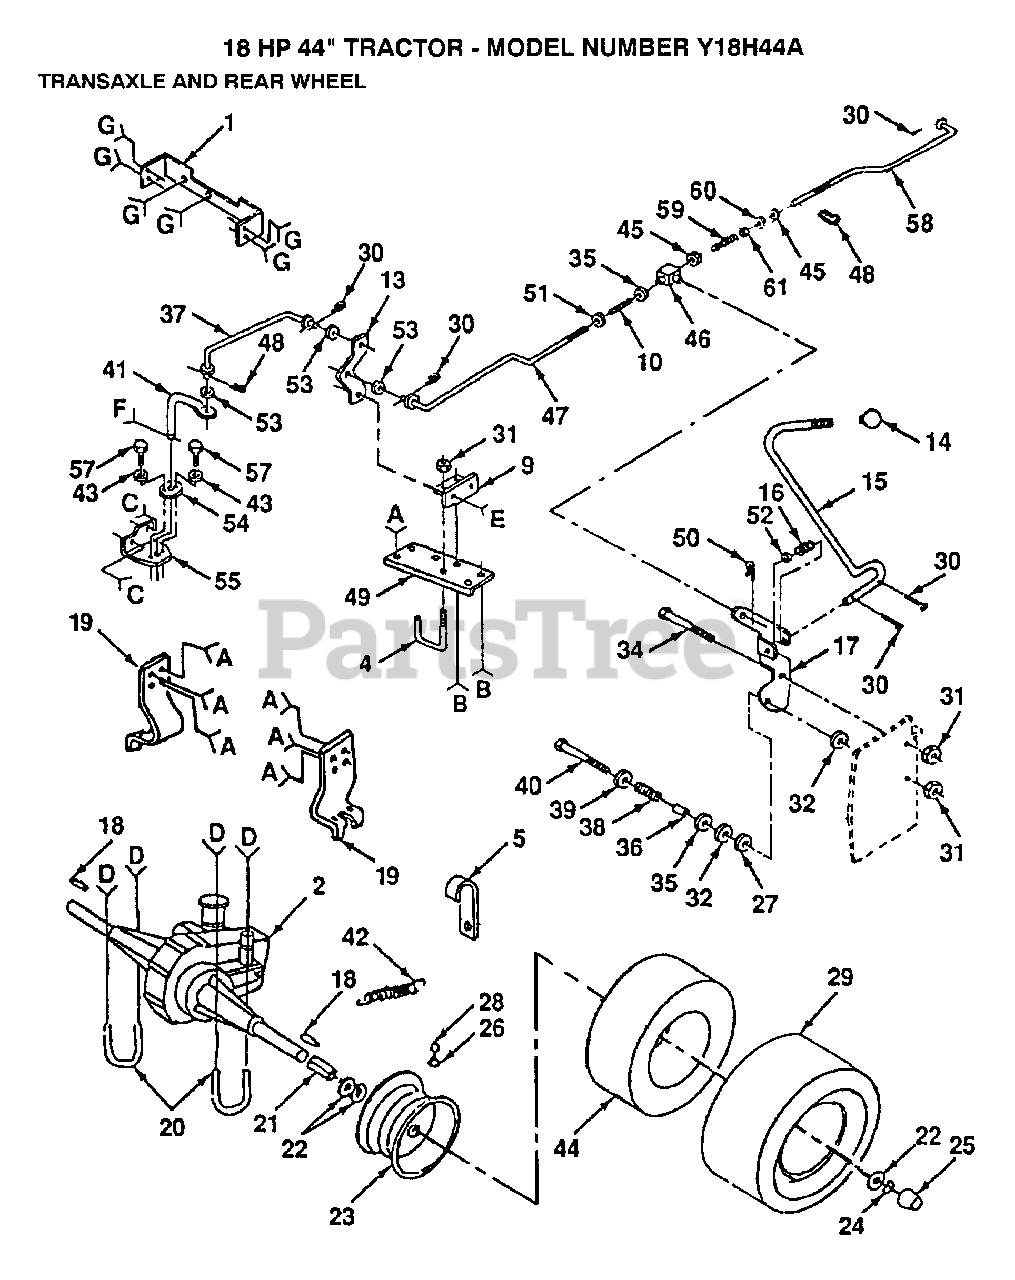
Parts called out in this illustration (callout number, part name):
1	PLATE TRANS SUPT
2	TRANSAXLE.AGRIFAB
4	KEEPER
5	CLIP T
9	BRKT BELLCRANK
10	SPRING GTV
13	BELLCRANK
14	KNOB.DUCKHEAD.1/2
15	ROD.YTH
16	SPRING TORSION
17	BRKT CONTROL HYT
18	SQUARE KEY
19	BRKT TRANSAXLE
20	U BOLT
21	SPACER SPLIT
22	WASHER
24	E-RING LT
25	HUB CAP
26	VALVE STEM LT
27	WASHER HYT
28	VALVE CAP
30	COTTER PIN
32	WASHER FRIC HYT
34	BOLT HYT
35	WASHER D
36	SPACER HYT
37	LINK CONTROL
38	SPRING HYT
39	WASHER
40	BOLT - HEX 3/8 - 16 X 3
41	ARM ASM PUMP
43	WASHER
44	TUBE.18X9.5-8
45	NUT
46	TRUNION HYT
47	ROD ADJ CONTROL
48	RETAINER M
49	BRACKET
50	SPRING.RETAINER
51	WASHER T
52	WASHER
53	WASHER T
54	GUIDE CONTROL
55	BRKT
57	SCREW
59	SPRING ROD LT
60	WASHER
61	NUT
